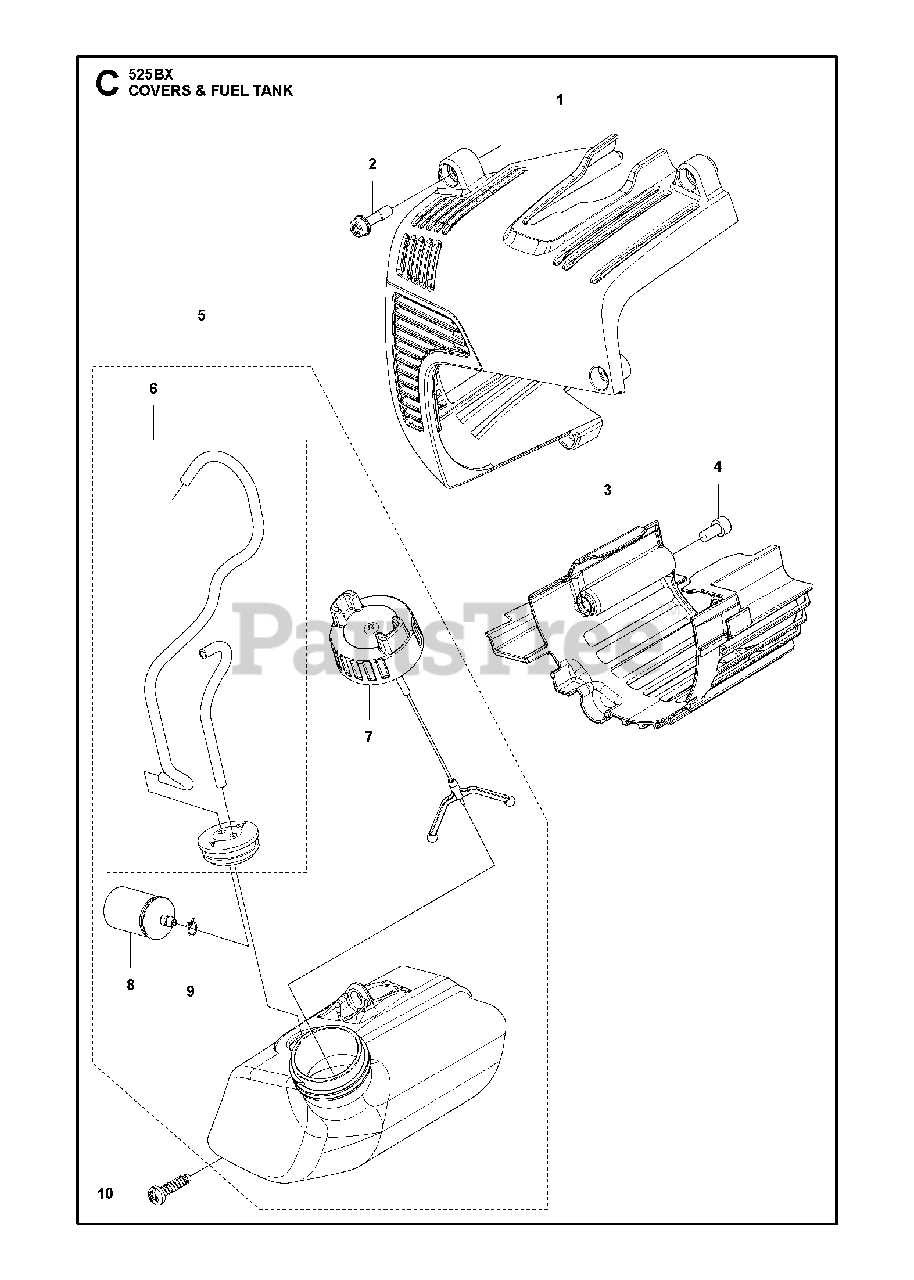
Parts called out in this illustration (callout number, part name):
1	ENGINE COVER
2	BOLT
3	PLATE MUFFLER GREY
4	BOLT 08
5	FUEL TANK ASSY EVP
5	FUEL TANK ASSY NO EVP
6	HOSE ASSY EVP
7	TANK CAP COMP
8	FUEL FILTER
10	SCREW, TORX (RPLS T4970-52001)
